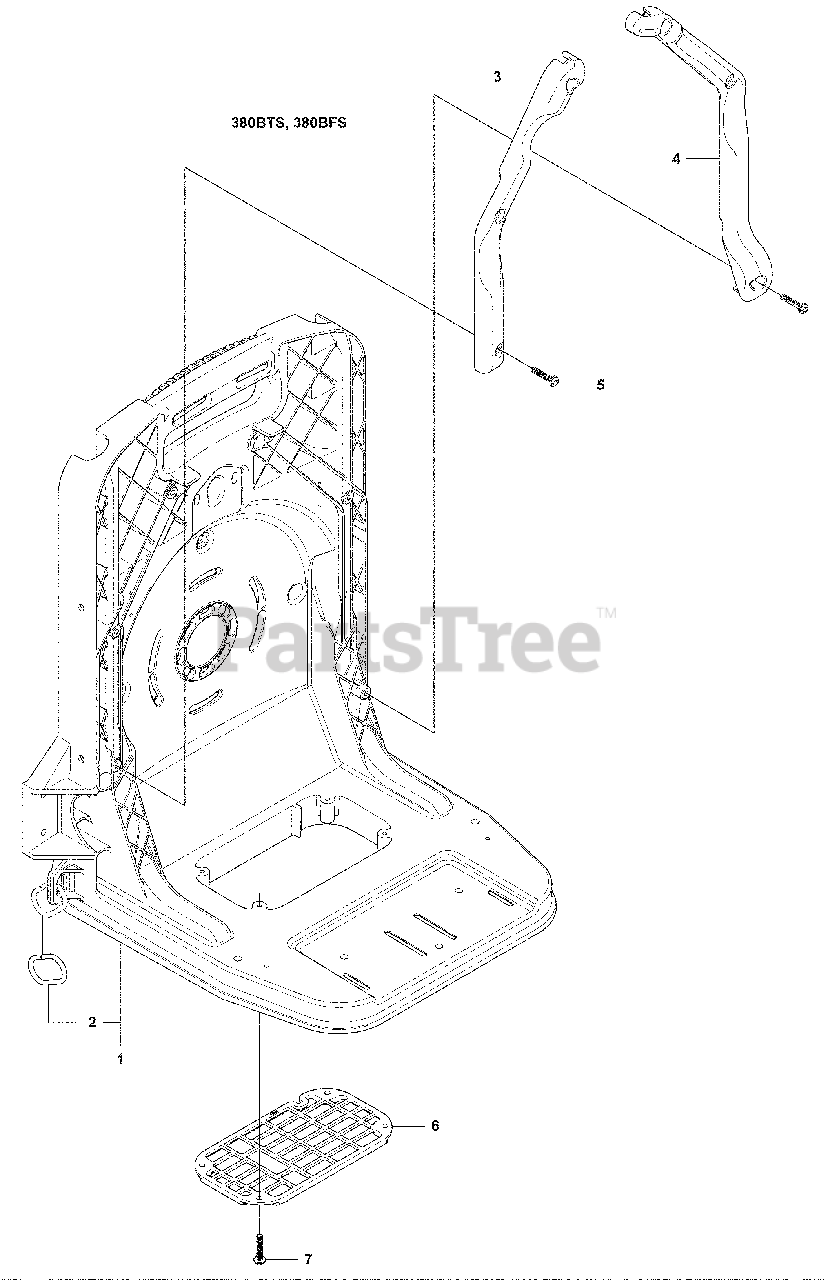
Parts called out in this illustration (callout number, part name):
2	Ring
5	Screw
7	Screw
